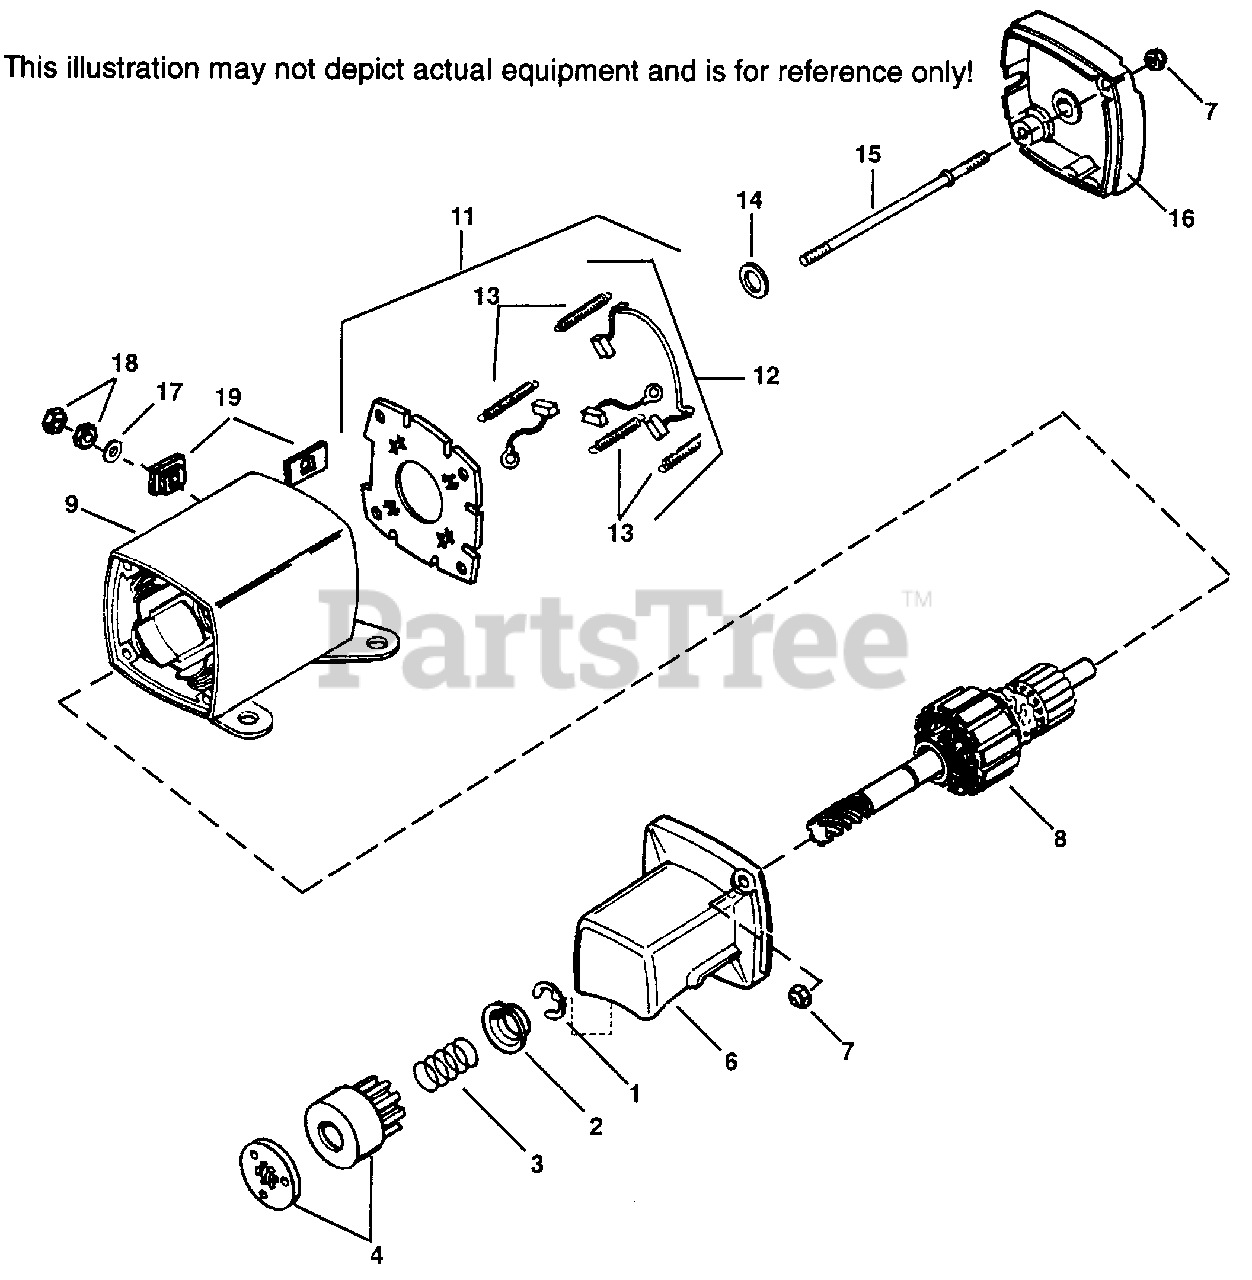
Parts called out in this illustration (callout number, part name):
1	Retainer Ring
2	Spring Retainer
3	Anti-drift Spring
4	Gear & Nut
6A	Drive End Cap Ass'y.
7	Lock Nut
8	Armature
9	Housing Ass'y.
11	Brush Card Ass'y. (Incl. 12)
12	Brush & Spring Kit (Incl. 13)
13	Brush Spring
14	Thrust Washer
15	Bolt, 10-32 x 3-17/32"
16	Commutator End Cap Ass'y.
18	Nut
19	Terminal Insulator
